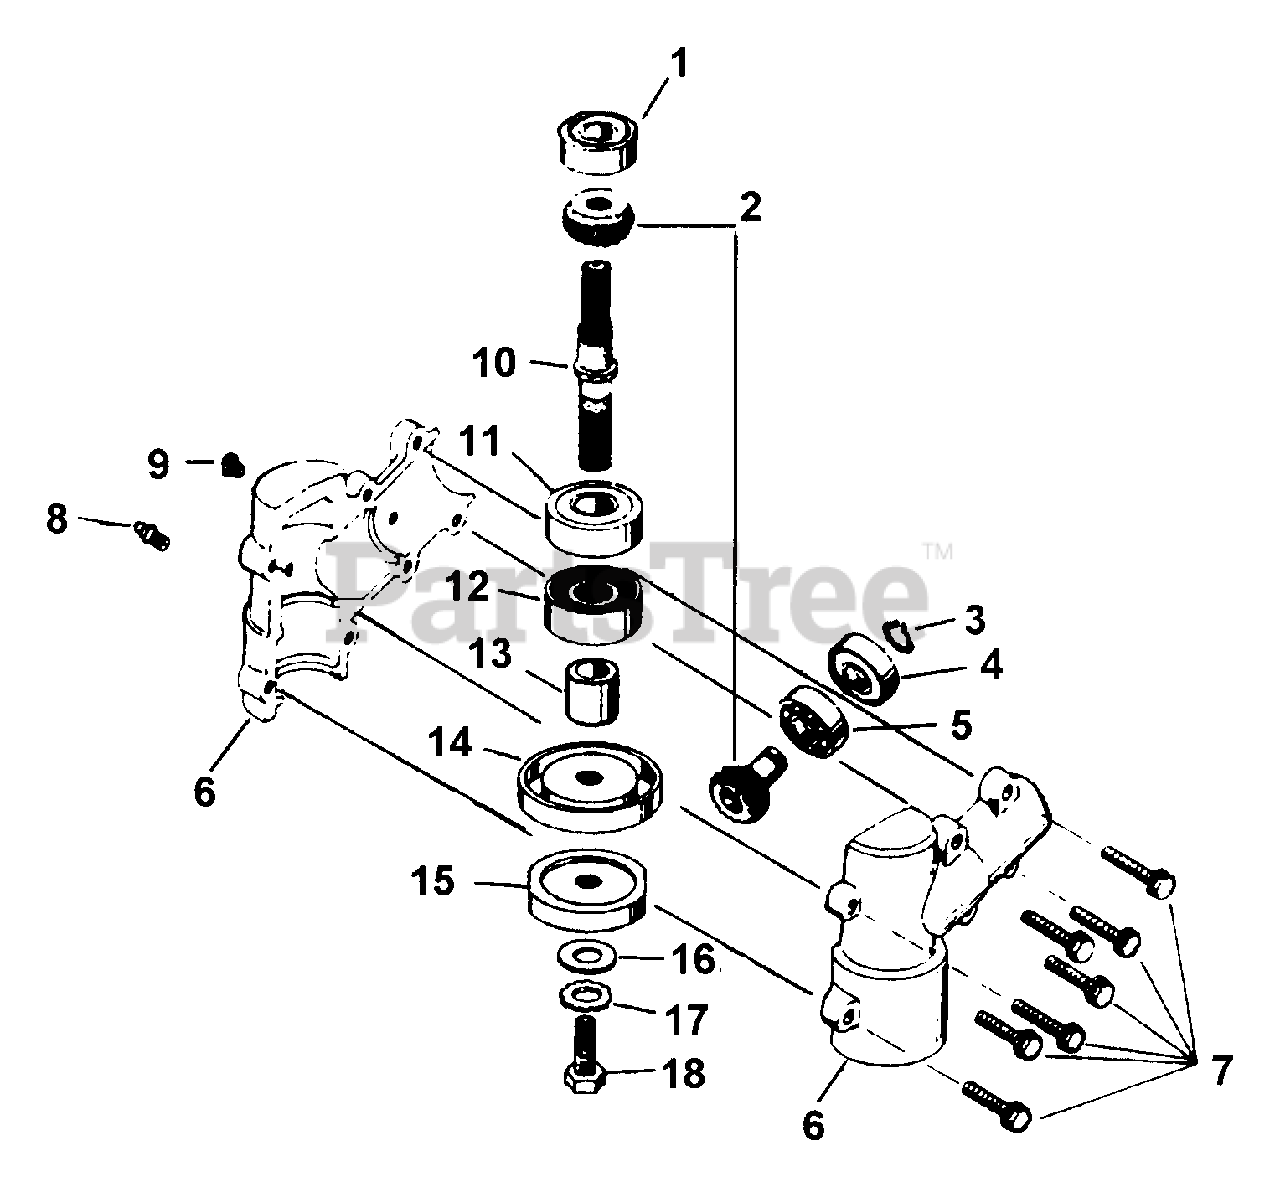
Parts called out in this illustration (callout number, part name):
1	BEARING
3	SNAP RING
4	BEARING
5	BEARING
6	HOUSING SET
7	SCREW, SELF TAPPING
8	GREASE FITTING
9	SCREW, SELF TAPPING
10	GEAR SHAFT
11	BEARING
14	UPPER FLANGE WASHER
15	LOWER FLANGE WASHER
16	WASHER, FLAT
17	WASHER, LOCK
18	BOLT
